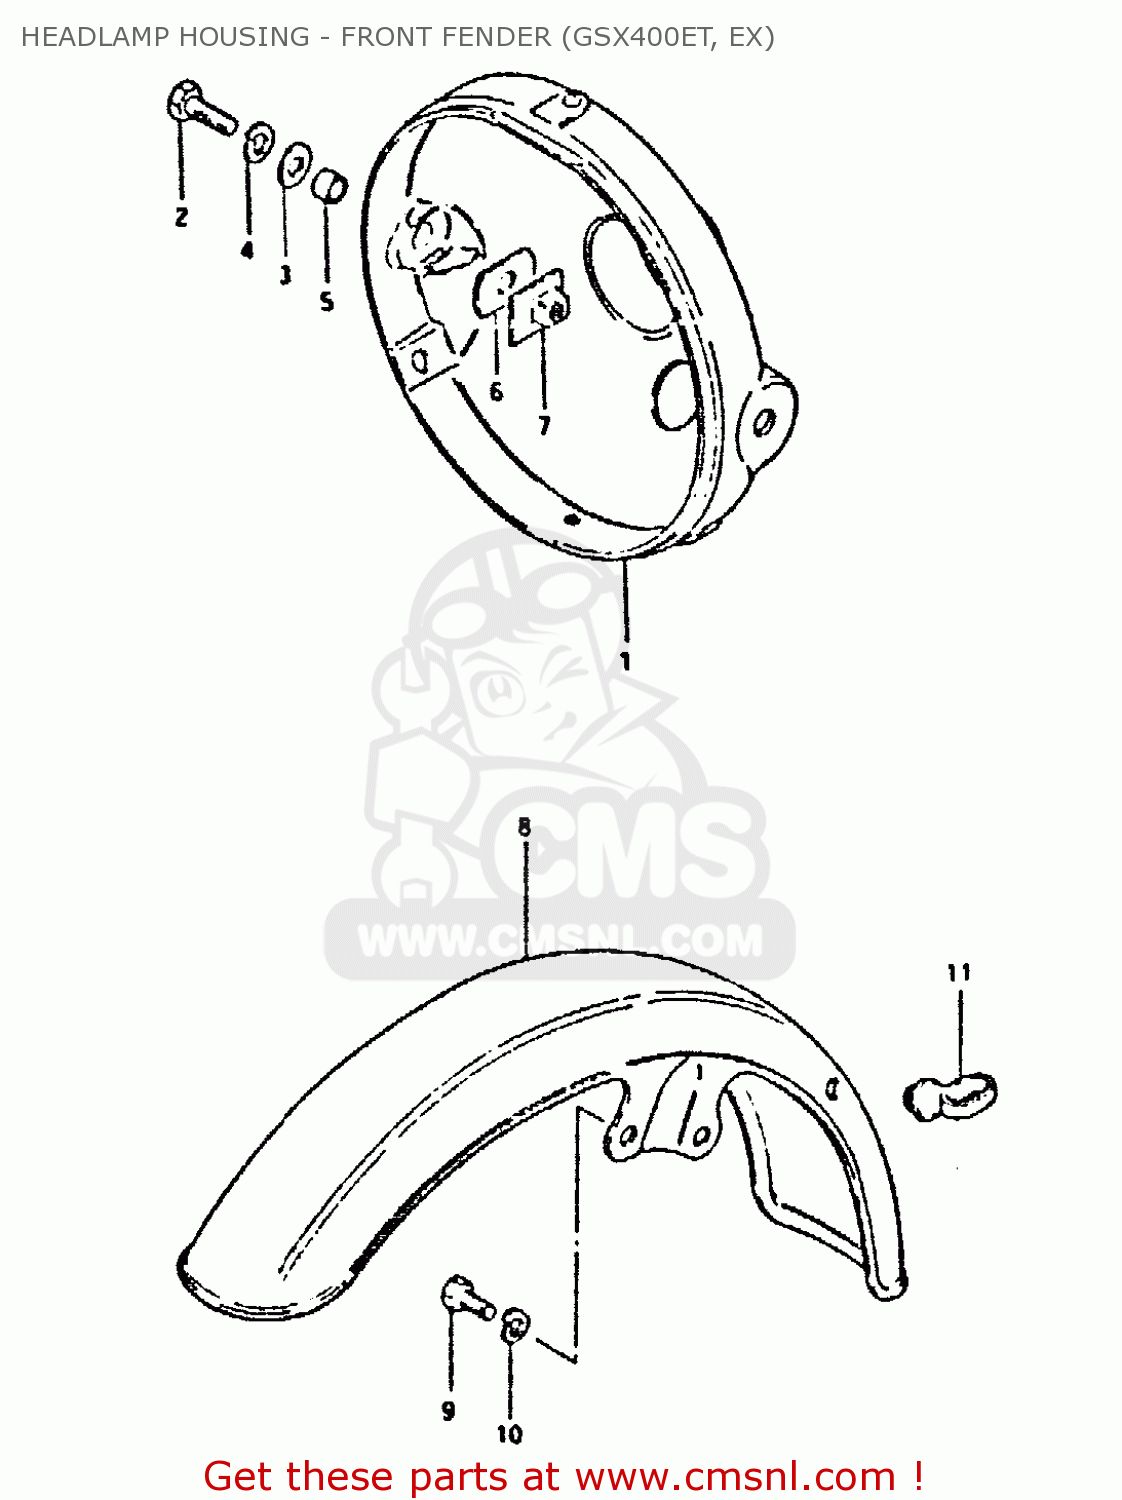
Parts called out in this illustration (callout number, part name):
1	HOUSING,HEADLAMP(BLACK)
2	BOLT
3	WASHER
4	LOCK WASHER
5	SPACER (8.8X12X7)
6	CUSHION
7	PLATE,HEADLAMP HOUSING
8	FENDER,FR
9	BOLT
10	LOCK WASHER
11	GUIDE,CABLE
